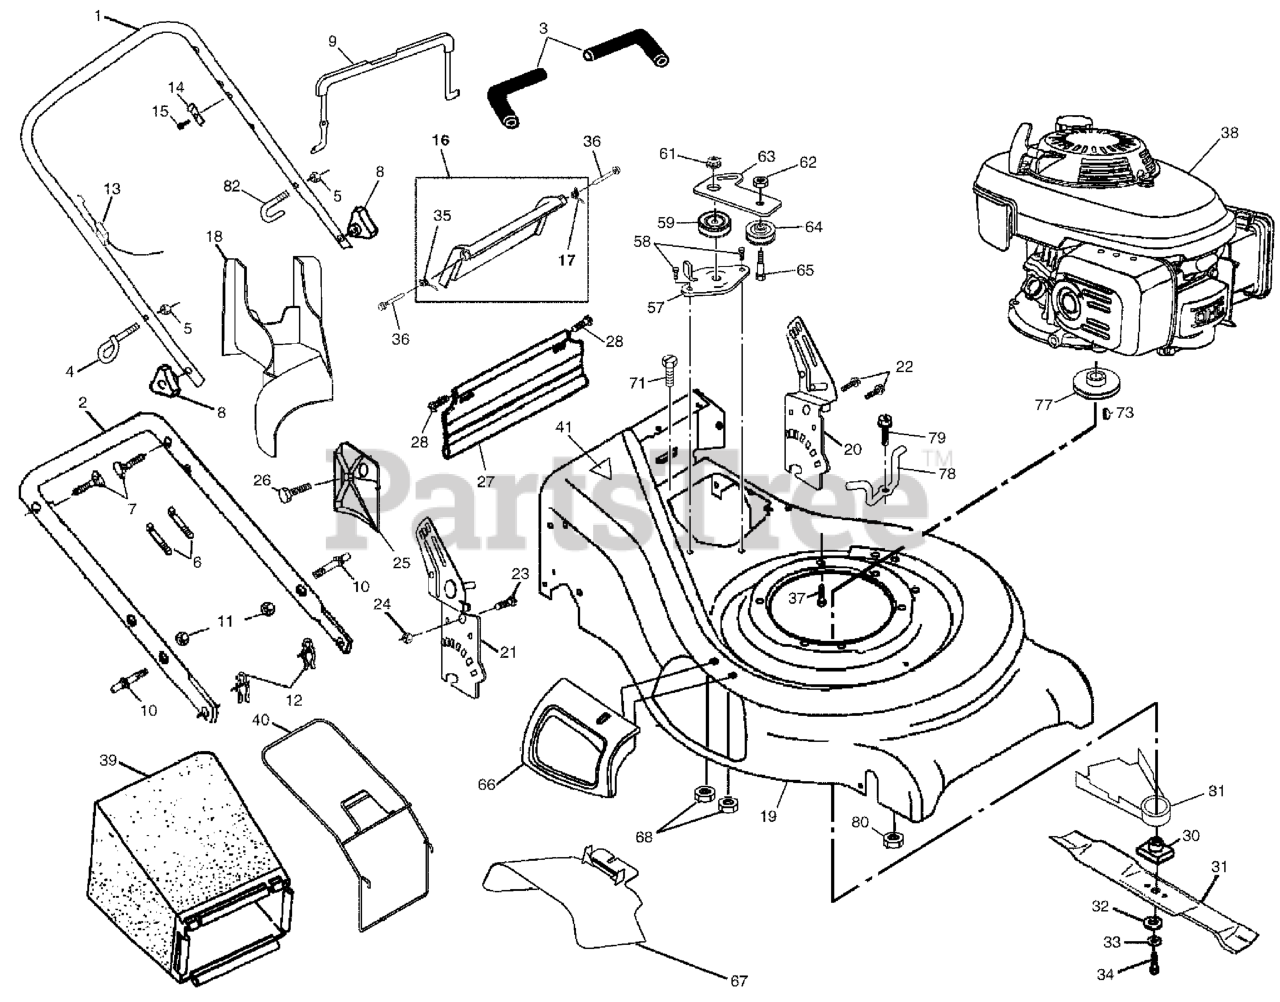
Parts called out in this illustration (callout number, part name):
1	HANDLE.UP.ASM.DSTRT/FLT
2	HANDLE, LOWER
3	GRIP.HANDLE.FOAM.WIDE.(1 SIDE)
4	ROPE, GUIDE
5	NUT
6	TIE GUIDE
7	HANDLE BOLT
8	KNOB.HANDLE.STAR.HUSQ.GRAY
9	BAIL, FLAT AUTO WALK
11	NUT.CENTERLOCK.5/16-
12	HAIRPIN COTTER
13	ENGINE ZONE CONTROL CABLE
14	BRACKET UPSTOP
16	DOOR.REAR.PLASTIC.21.RWGD.BLAC
17	SPRING.RH.REAR.DOOR.21.RWGD
18	PLUG, MULCHER
19	RP KIT.HSG.21.RGD.MC.ORAN
20	HANDLE BRACKET ASM. LH
21	HANDLE BRACKET ASM. RH
22	SELF-TAPPING SCREW 5/16-18X3/4
23	BOLT, HEX HEAD 5/16-18
24	NUT.71038.31-18.HEX.NYLOCK
25	CLIPPING DEFLECTOR
27	SKIRT, REAR
28	HINGE SCREW
30	BLADE ADAPTER
31	BLADE
32	WASHER,HARDEN
33	LOCKWASHER
34	SCREW, HEX HD 3/8-24 X 1-3/8
35	SPRING.LH.REAR.DOOR.21.RWGD
37	BOLT 3/8-16X1-1/8
39	GRASS CATCHER BAG
40	GRASS CATCHER FRAME
41	DECAL HYT
57	BRACKET ASSEMBLY
59	PULLEY ASSY
61	NUT
62	LOCKNUT
63	IDLER ARM
64	IDLER PULLEY
65	SHOULDER BOLT
66	MULCHER DOOR ASM.
67	DEFLECTOR, DISCHARGE
73	HI-PRO KEY
77	PULLEY.ENG.25MMM
78	KEEPER.BELT.21.RWGD.EZ
79	SCREW.#8.MACH
80	NUT.HEX.#8
81	SHIELD.DEBRIS.ASM.21.RWGD
